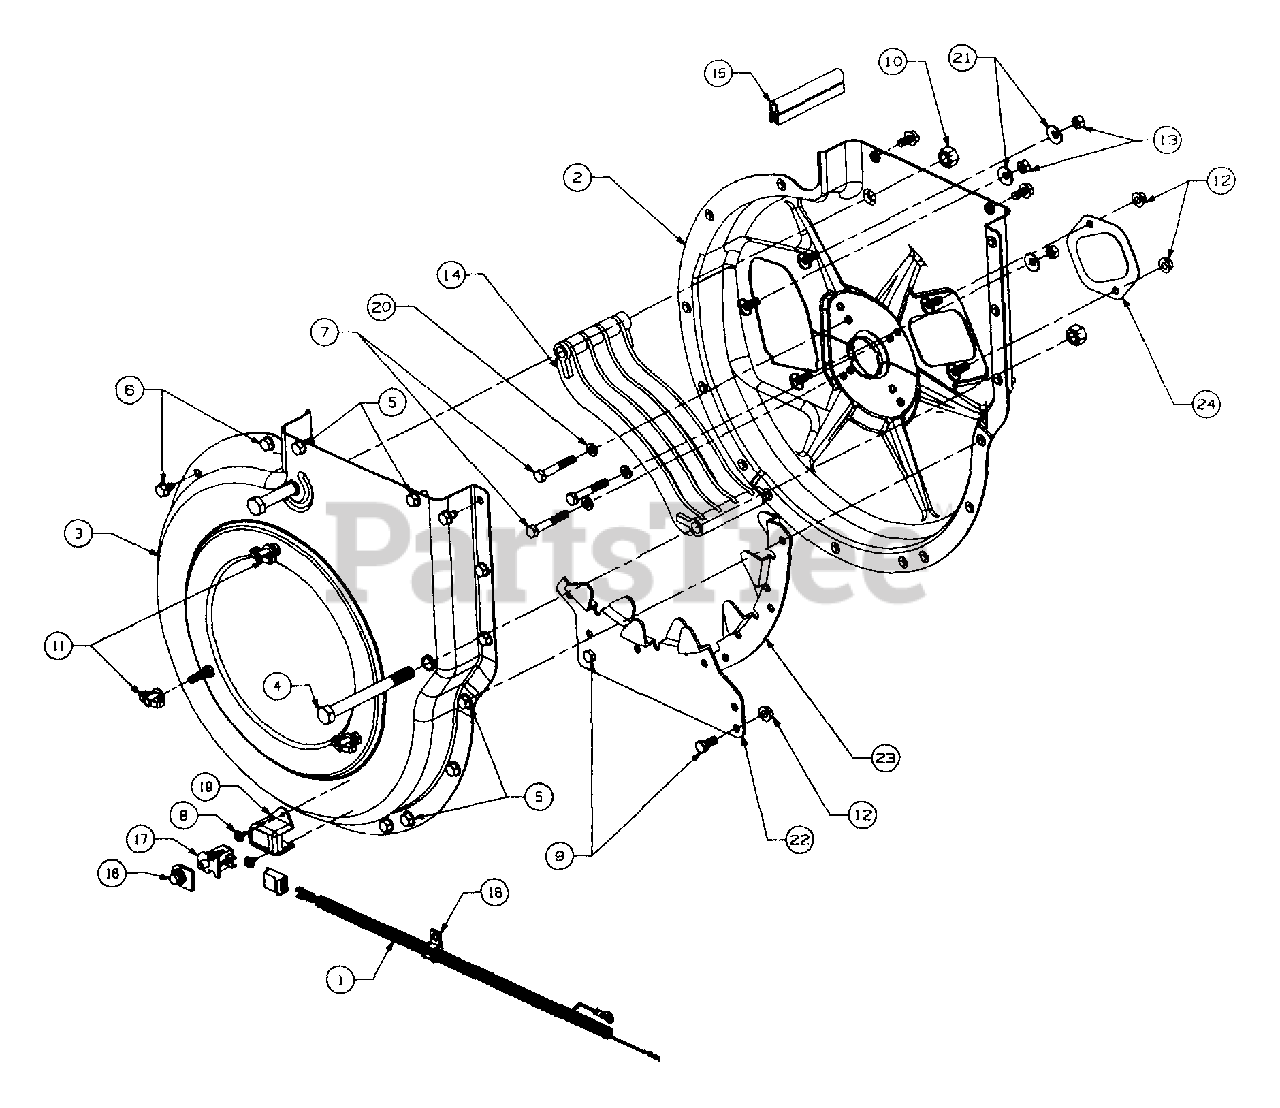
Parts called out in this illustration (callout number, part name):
1	HARNESS - CHIPPER VAC
5	SCREW - HEX SELF TAP
6	SCREW - HEX SELF TAP
8	SCREW - HEX SELF TAP
10	NUT - HEX LOCK
12	NUT - HEX LOCK
13	NUT - HEX (GR 5)
15	SEAL - RUBBER
16	COVER - SWITCH
17	SWITCH
19	COVER SWITCH
20	WASHER - LOCK
21	WASHER - BELL
